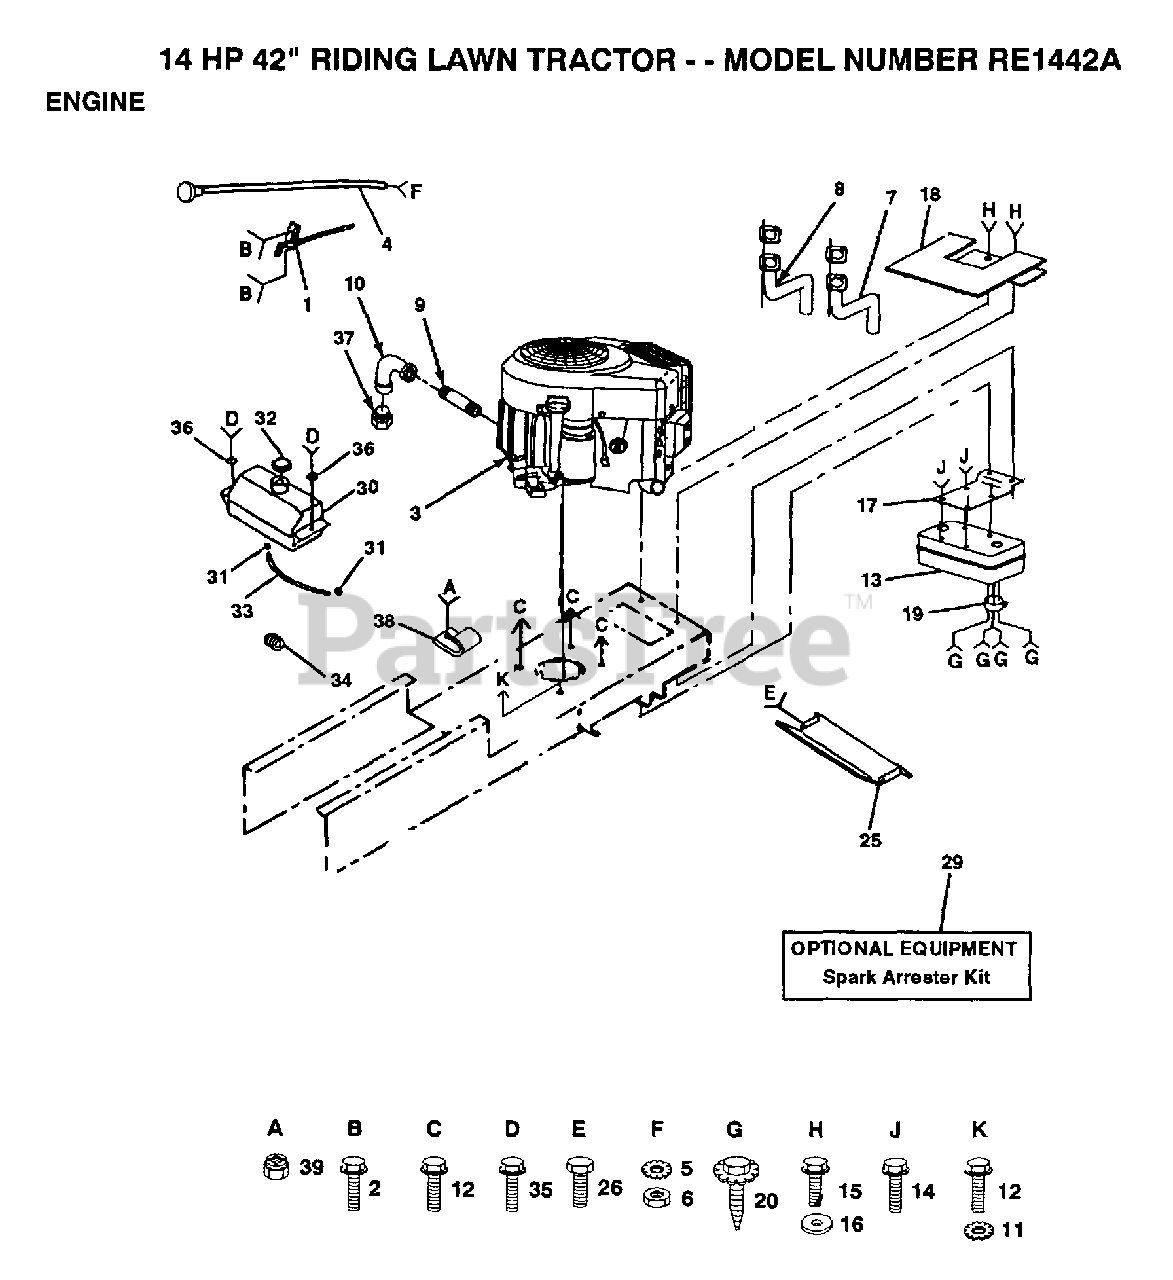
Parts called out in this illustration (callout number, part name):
2	SCREW LT
5	LOCKWASHER
7	TUBE ASSY EXH LH
8	TUBE ASSY EXH RH
9	PIPE NIPPLE LT
10	ELBOW
11	LOCKWASHER
12	SCREW
14	SCREW ST
15	SCREW
16	WASHER
17	BRACKET MUFFLER
19	DEFLECTOR.222573
25	HEAT SHIELD
26	SCREW
29	SPARK ARREST KIT
30	TANK.FUEL.LT.
31	HOSE CLAMP
33	FUEL LINE T
35	SCREW HEX CRT
36	WASHER
38	CLIP T
